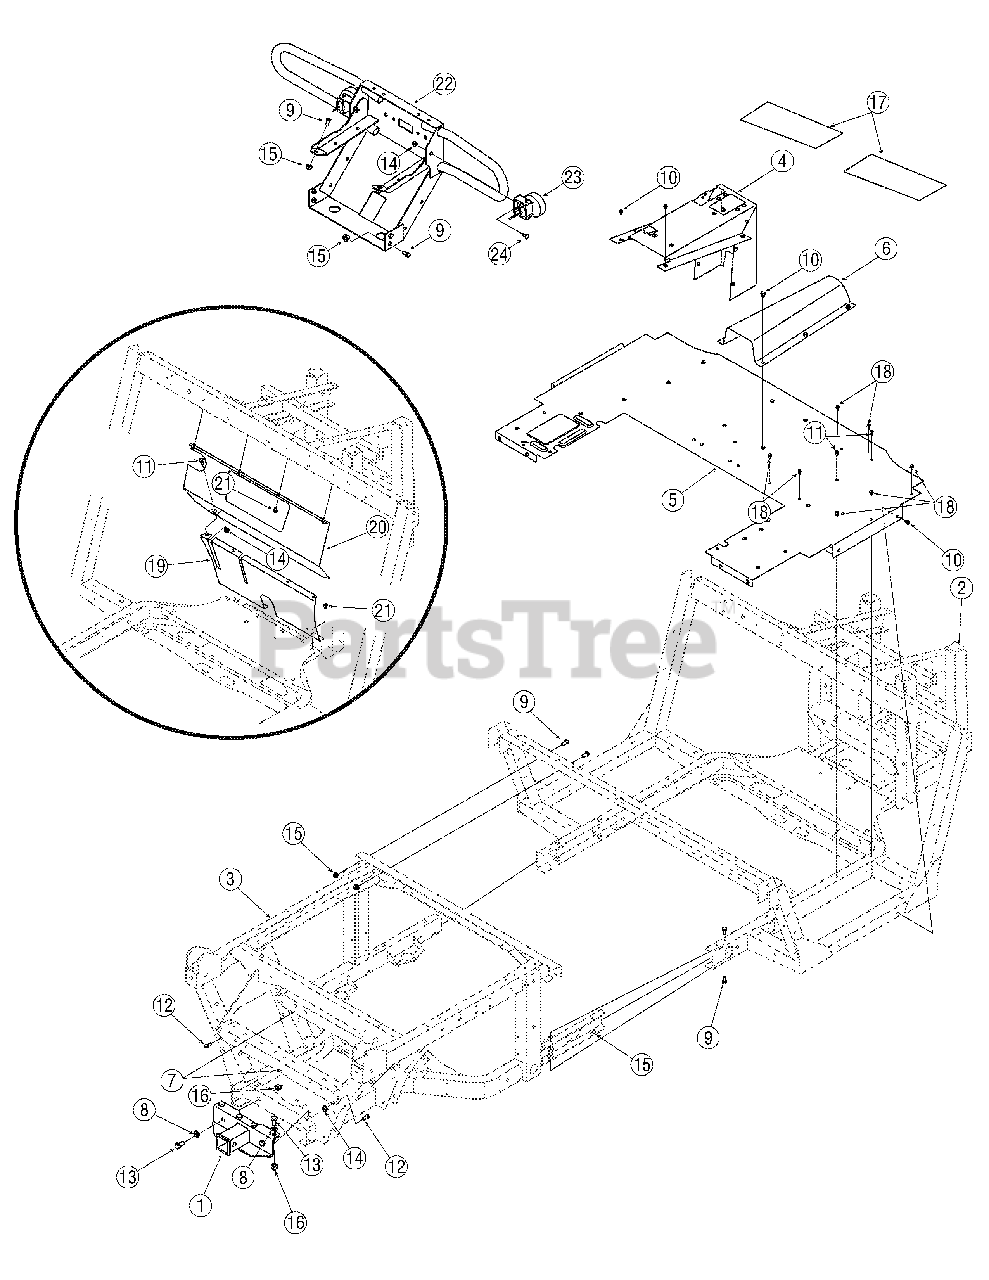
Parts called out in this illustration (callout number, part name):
2	Frm Assembly, front, uv
8	Washer, Flat, .510 x 1.00 x .060
9	Screw, 3/8-16, .75, gr5, std
10	Scr, tt, 5/16-18, 0.500, hxindwsh
11	Scr, ab, 1/4-14, 0.625, trustrxi
12	Screw, 5/16-18, .75, gr5, std
13	Screw, 1/2-13, 1.00, gr5, std
14	Nut, flglk, 5/16-18, grf, nylon
15	Nut, flglk, 3/8-16, grf, nylon
16	Nut, hexlk, 1/2-13, grb, nylon
17	Pad, abrasive, toe Plate
18	Clip, pnl, ret,
21	Scr, tt, 1/4-20 x .500
23	Lamp, Fog
24	Bolt, Carriage, 5/16-18 x .750
